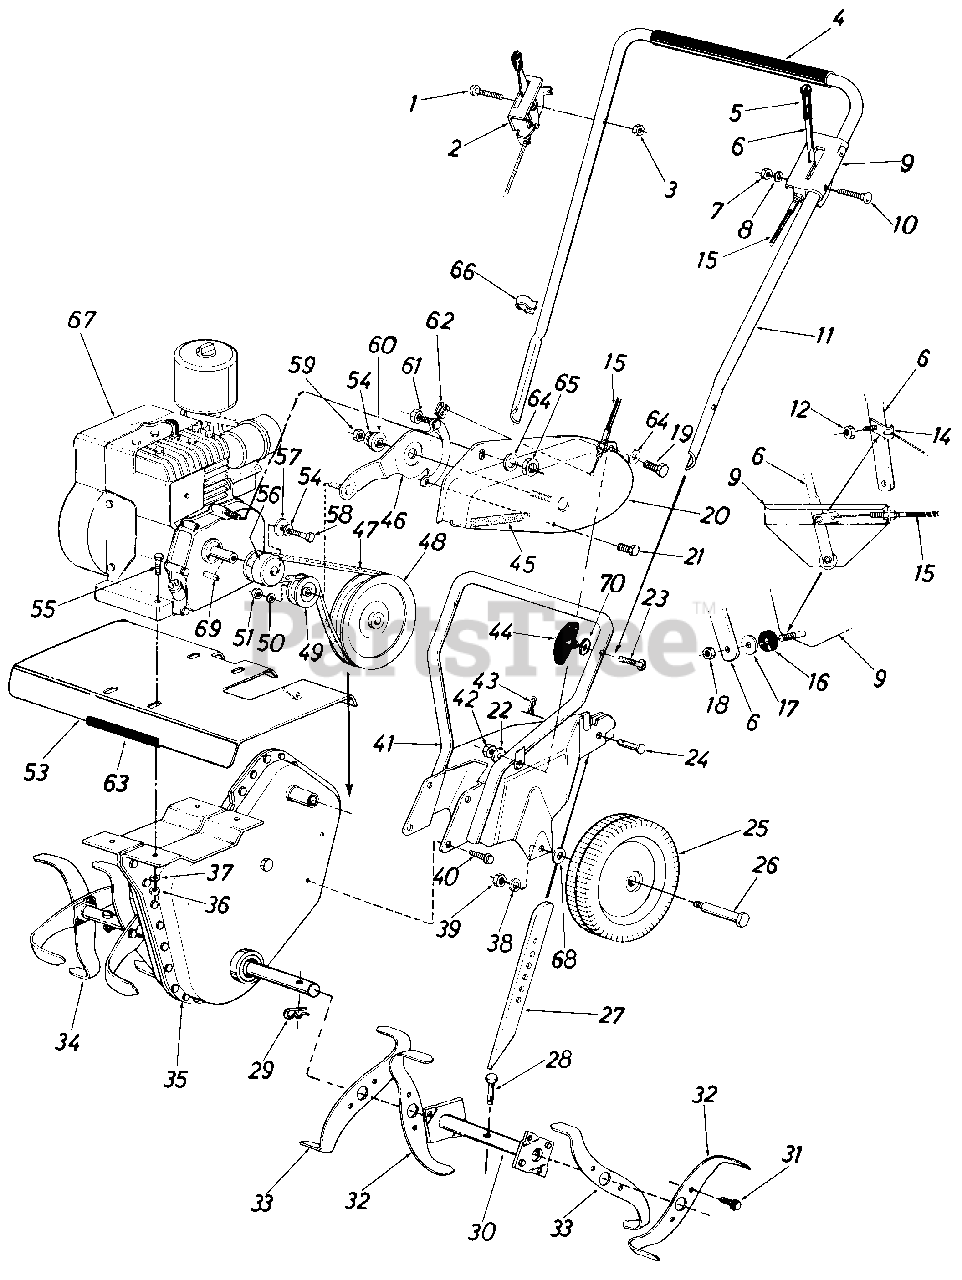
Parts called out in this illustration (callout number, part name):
1	Hex Bolt 1/4-20 x 1.50" Lg.
2	Throttle Control Ass'y. Comp.
3	Hex Cent. L-Nut 1/4-20 Thd.
4	Grip-14" Lg.
5	Handle Grip
6	Clutch Handle Ass'y.
7	Hex Cent. L-Nut 1/4-20 Thd.
8	Fl-Wash. 1/4" I.D. x .50" O.D. x .063
9	Clutch Handle Brkt. Ass'y.
10	Carr. Bolt 1/4-20 x 1.25" Lg.
11	Upper Handle
12	Hex Cent L-Nut 1/4-20 Thd.
14	Clevis
15	Clutch Cable
16	Rubber Wash.
17	Fl-Wash. 1/4" I.D. x .75" O.D. x .063
18	Hex Cent. L-Nut 1/4-20 Thd.
19	Hex Bolt 1/4-20 x .75" Lg.
20	Belt Cover Ass'y.
21	Hex Wash. Hd. Tap Scr. 1/4 x .50
22	L-Wash. 1/4" I.D.
23	Curved Hd. Bolt 5/16-18 x 1.75" Lg.
24	Clevis Pin
25	Wheel Ass'y.-7"
26	Shoulder Bolt
29	Hairpin Cotter
36	Hex Nut 5/16-18 Thd.
37	L-Wash. 5/16" Scr.
38	L-Wash. 3/8" Scr. H.D.
39	Hex Cent. L-Nut 3/8-16 Thd.
40	Hex Wash. SF-Tap Scr. 5/16-18 x .50" Lg.
43	Intern. Cotter Pin
44	Hand Knob
45	Extension Spring .60 O.D. x 4.88" Lg.
46	Idler Arm Ass'y.
47	Belt 3/8" x 29" Lg.
48	Chain Case Pulley 51/2 x 1/2"
49	Fl-Idler 2"
50	L-Wash. 5/16" Scr.
51	Hex Nut 3/8-24 Thd.
55	Hex Bolt 5/16-18 x 1.50" Lg.
56	Engine Pulley 3/8 V x .7525 I.D. x 2" O.D.
57	Fl-Wash. .385 I.D. x 1.00" O.D. x .135
58	Hex Bolt 3/8-24 x 1.00" Lg.
59	Hex Nut 5/16-18 Thd.
60	Shld. Spacer. 50" Dia. x .133
61	Hex Cent. L-Nut 1/4-20 Thd.
62	Clevis
63	Trim Strip-4"
64	L-Wash. 1/4" I.D.
65	Hex Cent. L-Nut 1/4-20 Thd.
66	Cable Tie
67	Eng i ne
68	Bel l-Wash.
69	Square Key 3/16 x 3/4" Lg.
70	Belleville Washer
